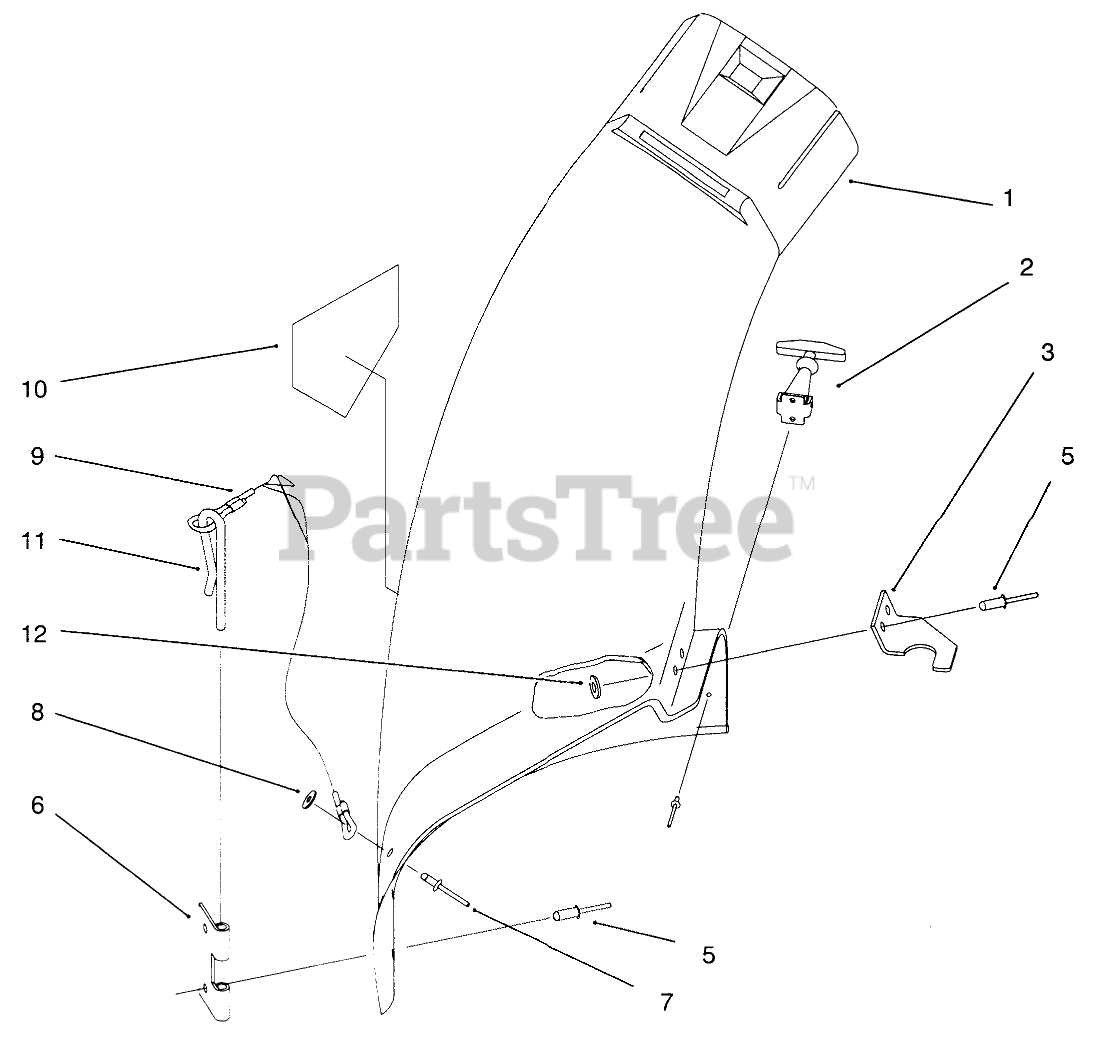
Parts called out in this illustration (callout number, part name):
1	ELBOW-BAGGER, 38 INCH
2	Latch-38"
3	LATCH-ELBOW, BAGGER
4	RIVET-POP
5	RIVET-BLIND
6	BRACKET-MOUNTING, CHUTE
7	RIVET-BLIND
8	WASHER-PLAIN
9	LANYARD
10	DECAL-DANGER
11	PIN-LOCKING, CHUTE
12	WASHER-FLAT
